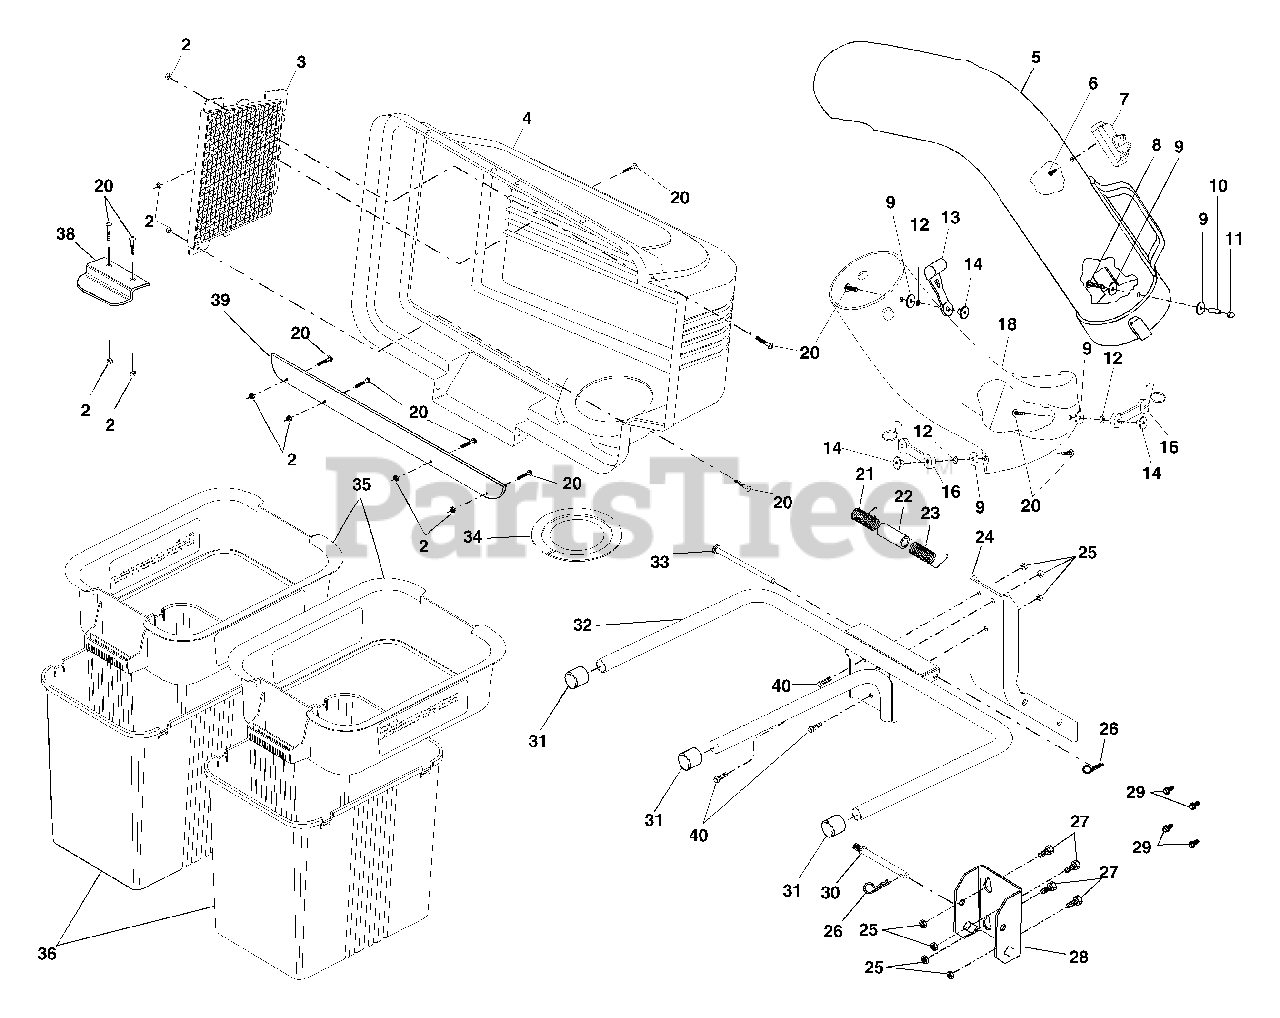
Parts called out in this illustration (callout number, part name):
2	Nut, Crownlock #10-24
3	Screen, Cover
4	Cover Asm.
6	Screw, Special #10-14x1/2
7	Dump Bag Indicator
8	Screw, #10-24 x 1-1/8
10	Spacer, Split
11	Nut, Acorn #10-24
12	Washer, lock #10
14	Nut, Weld
16	Latch Hook Asm.
20	Screw #10-24 x 5/8
21	Spring, Cover L.H. (black)
22	Spacer, Cover
23	Spring, Cover R.H. (gray)
24	Post, Support
25	Locknut 5/16 x 18
26	Spring, Retainer
27	Bolt, Hex 5/16-18 x 3/4
28	Bracket, Mounting
29	Shoulder Bolt
30	Pin, Support Post
31	Plug, Tubing End
32	Bagger, Frame
33	Pin, Hinge
34	Gasket, Cover
35	Container, Top
36	Container, Bottom
38	Latch Handle, Cover
39	Strip, Reinforcement
40	Carriage Bolt 5/16-18x3/4
